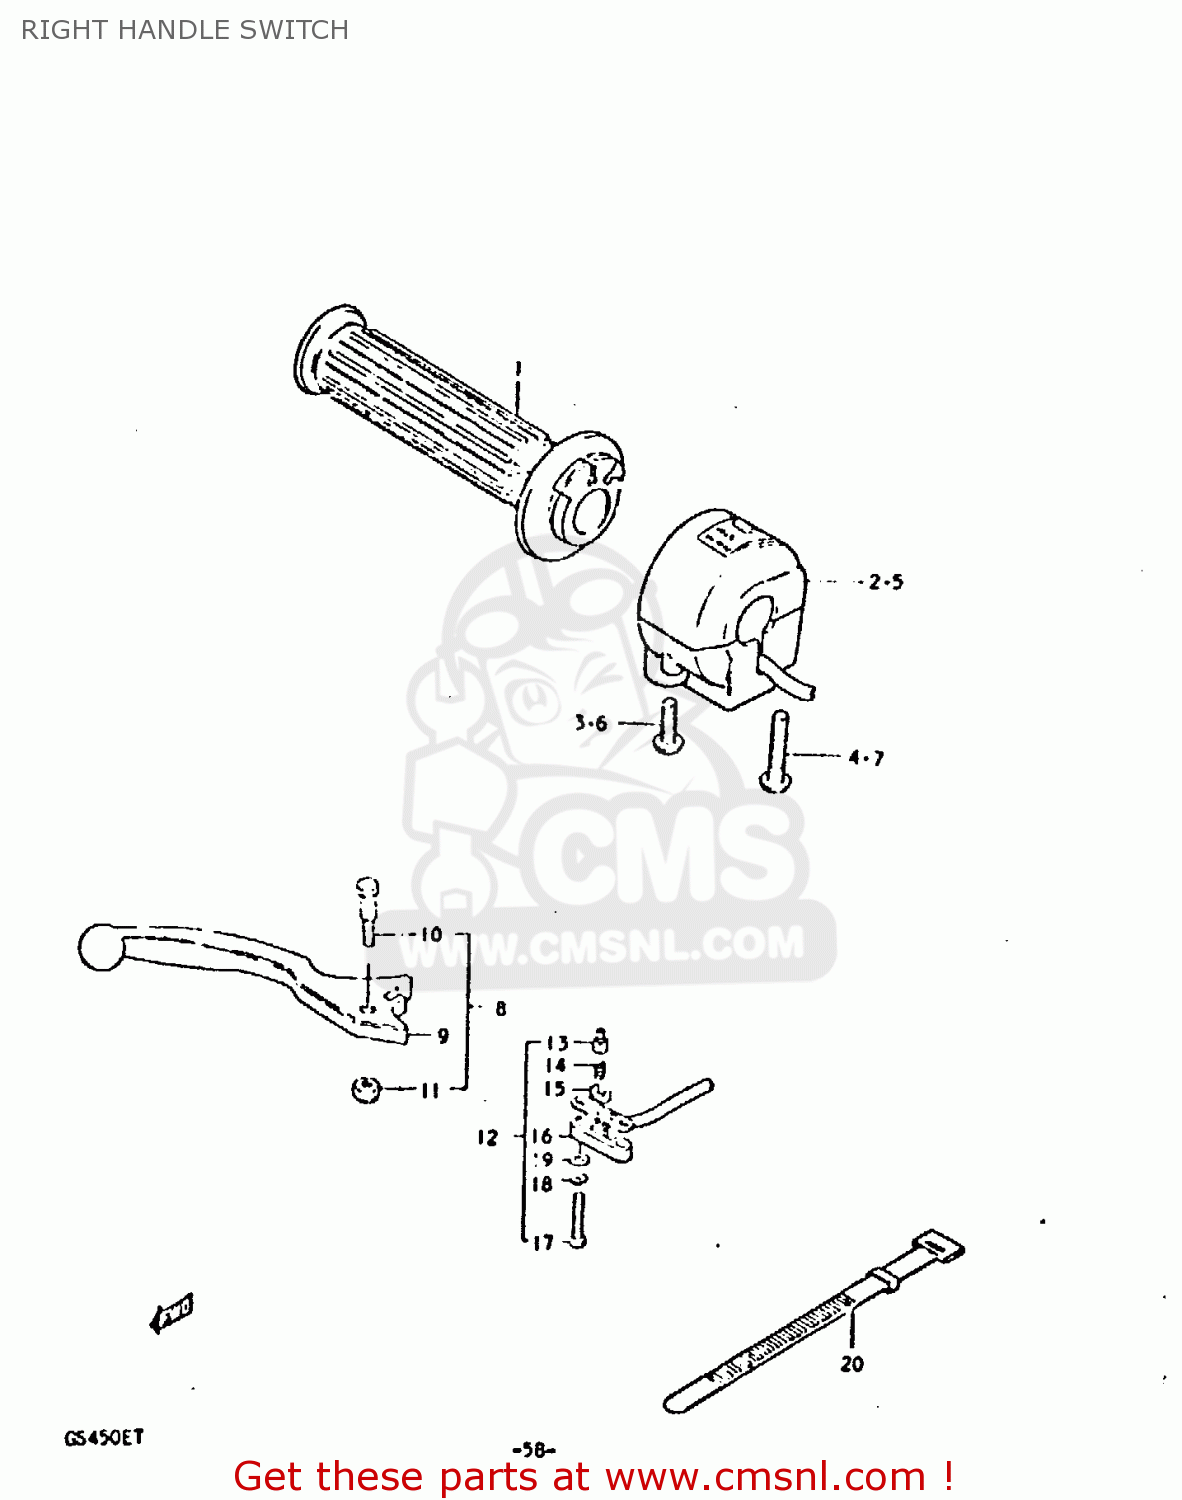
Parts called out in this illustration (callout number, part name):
1	GRIP,THROTTLE
2	SWITCH ASSEMBLY,HANDLE,RIGHT
3	SCREW
4	SCREW
8	LEVER ASSEMBLY,BRAKE
9	LEVER,BRAKE
10	BOLT
11	NUT 6MM
20	CLAMP(L:120)
